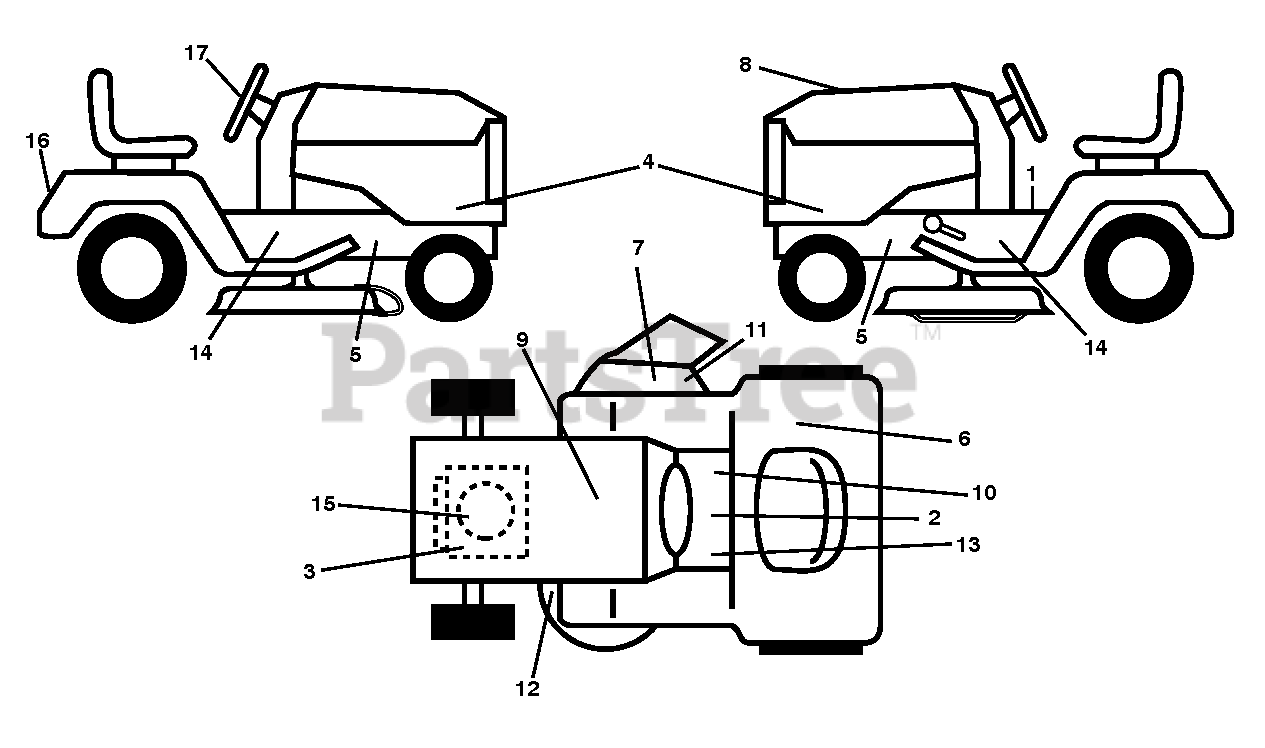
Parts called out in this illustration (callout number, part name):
7	DECAL.INTERNATIONL.CUTFINGER
9	DECAL BTRY SYMBOLS
10	DECAL PARK BRAKE
11	DECAL, DEFLECT WARNING
12	DECAL V BELT SCHEMATIC
